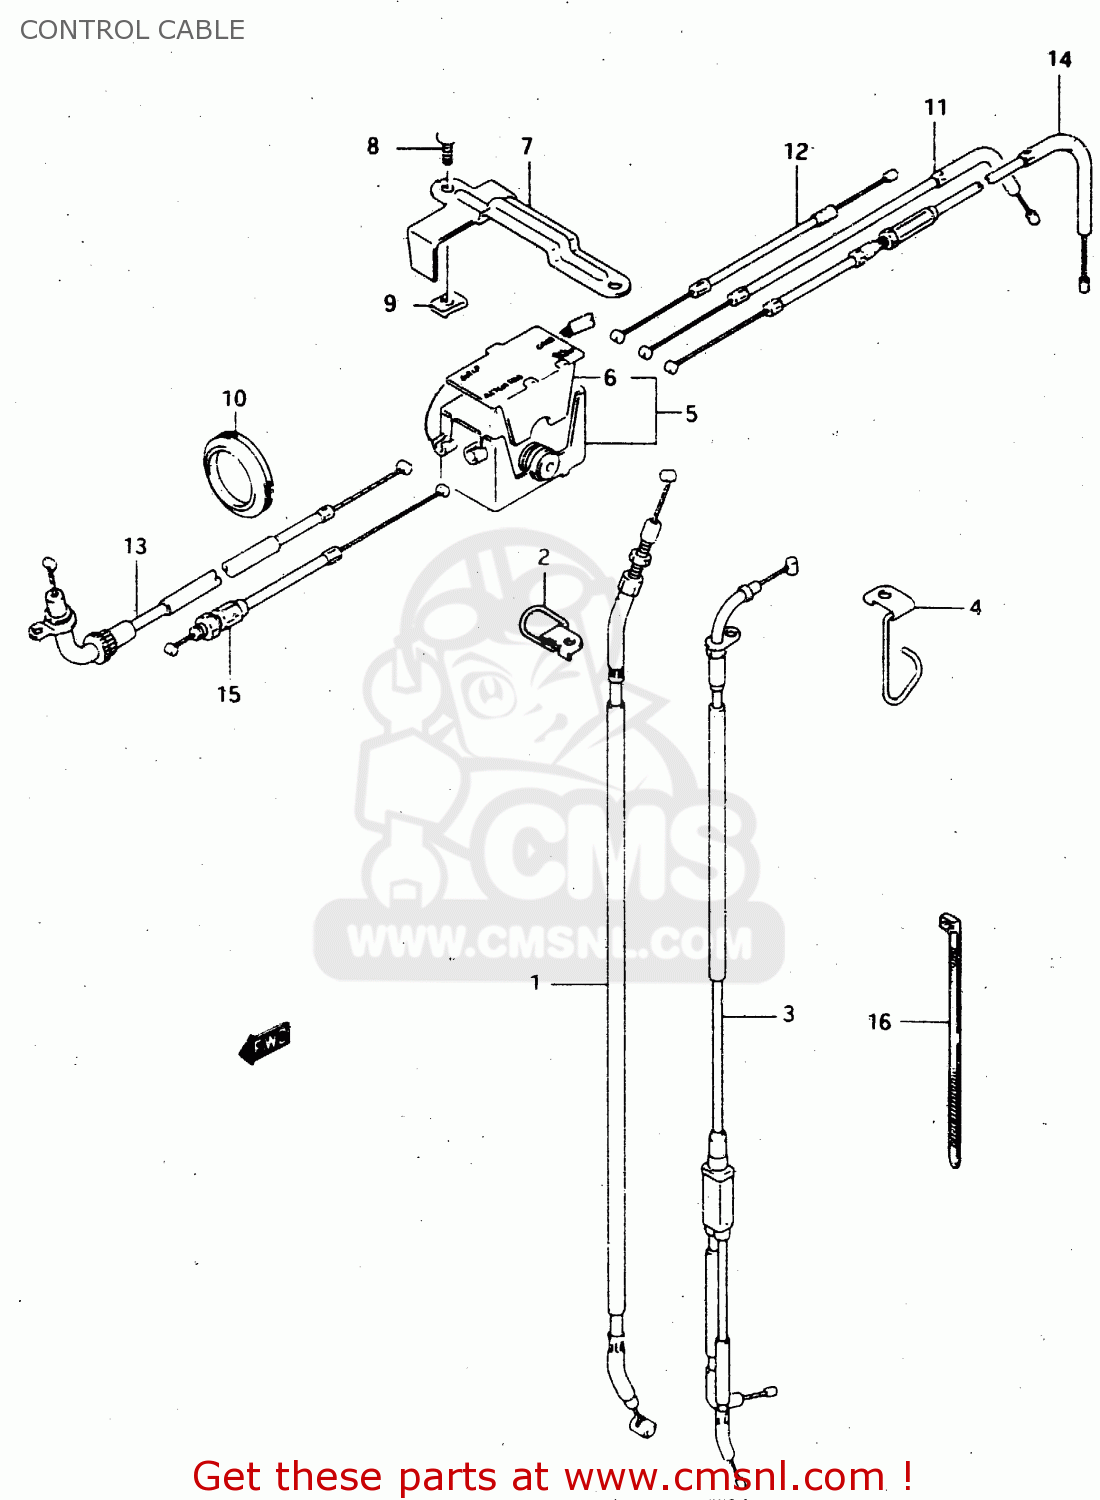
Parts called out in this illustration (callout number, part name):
1	CABLE ASSY,CLUTCH
2	GUIDE, CLUTCH CABLE
3	CABLE,STARTER
4	GUIDE,STARTER CABLE
5	SENSOR SET, THROTTLE
6	COVER,THROTTLE CABLE CONN
7	PLATE, CONNECTO BOX
8	SCREW
9	NUT
10	GROMMET
11	CABLE,THROTTLE NO.1
12	CABLE,THROTTLE NO.2
13	CABLE,THROTTLE NO.3
14	CABLE,THROTTLE NO.4
15	CABLE,THROTTLE NO.5
16	CLAMP
